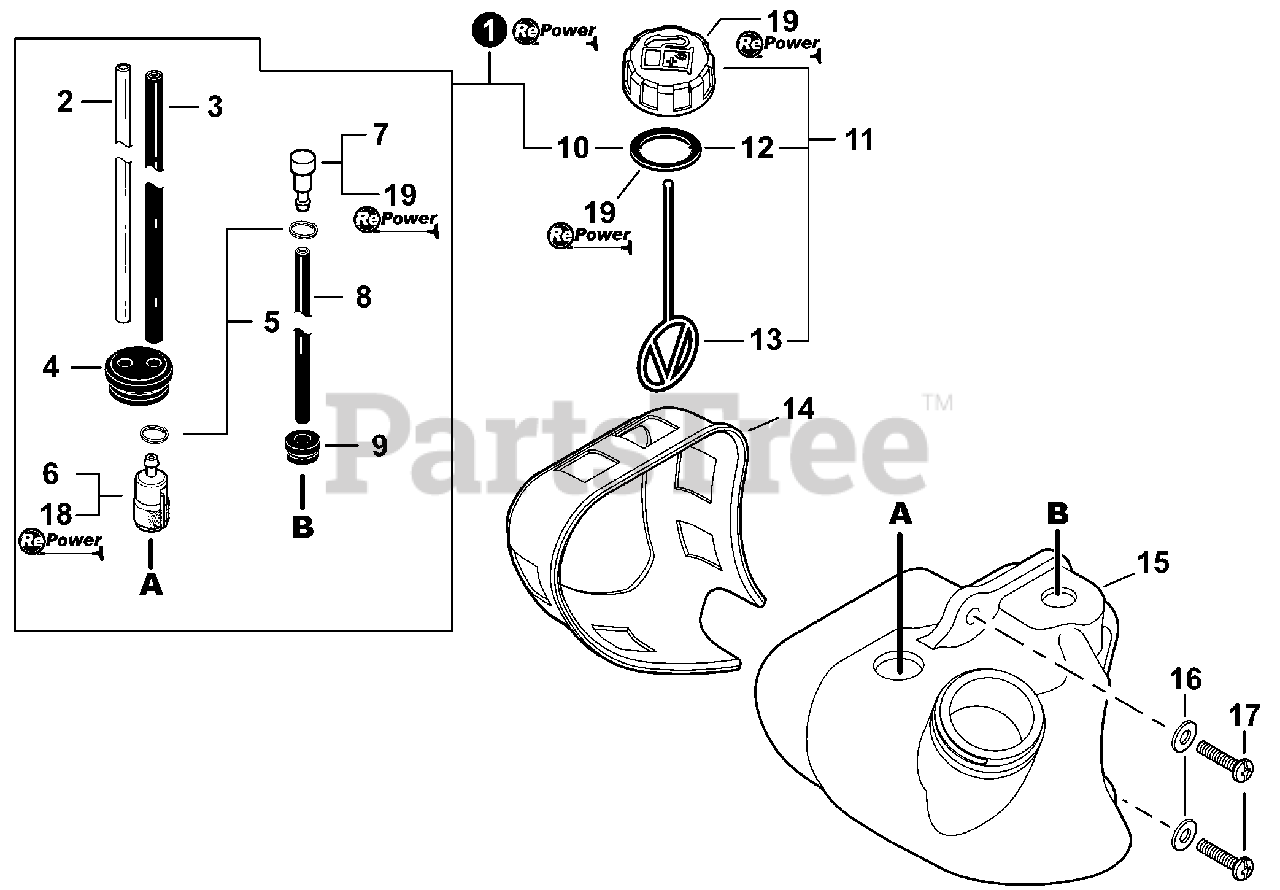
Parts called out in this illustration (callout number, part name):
1	FUEL SYSTEM KIT
2	PIPE, FUEL 3×6×85 CLEAR
3	PIPE, FUEL 3×5×175 BLACK
4	GROMMET, FUEL
5	CLIP 6 MM
6	FILTER, FUEL
7	VENT ASSY
8	PIPE, FUEL VENT 3×5×50
9	GROMMET
10	GASKET, FUEL CAP
11	CAP ASSY, FUEL
12	GASKET, FUEL CAP
13	CONNECTOR, CAP L= 100 MM
14	GUARD, FUEL TANK
15	TANK, FUEL
16	WASHER 5.5×12×0.8
17	SCREW, TAPPING 5×20
18	TUNE-UP KIT - REPOWER
19	CAP/VENT KIT - REPOWER
